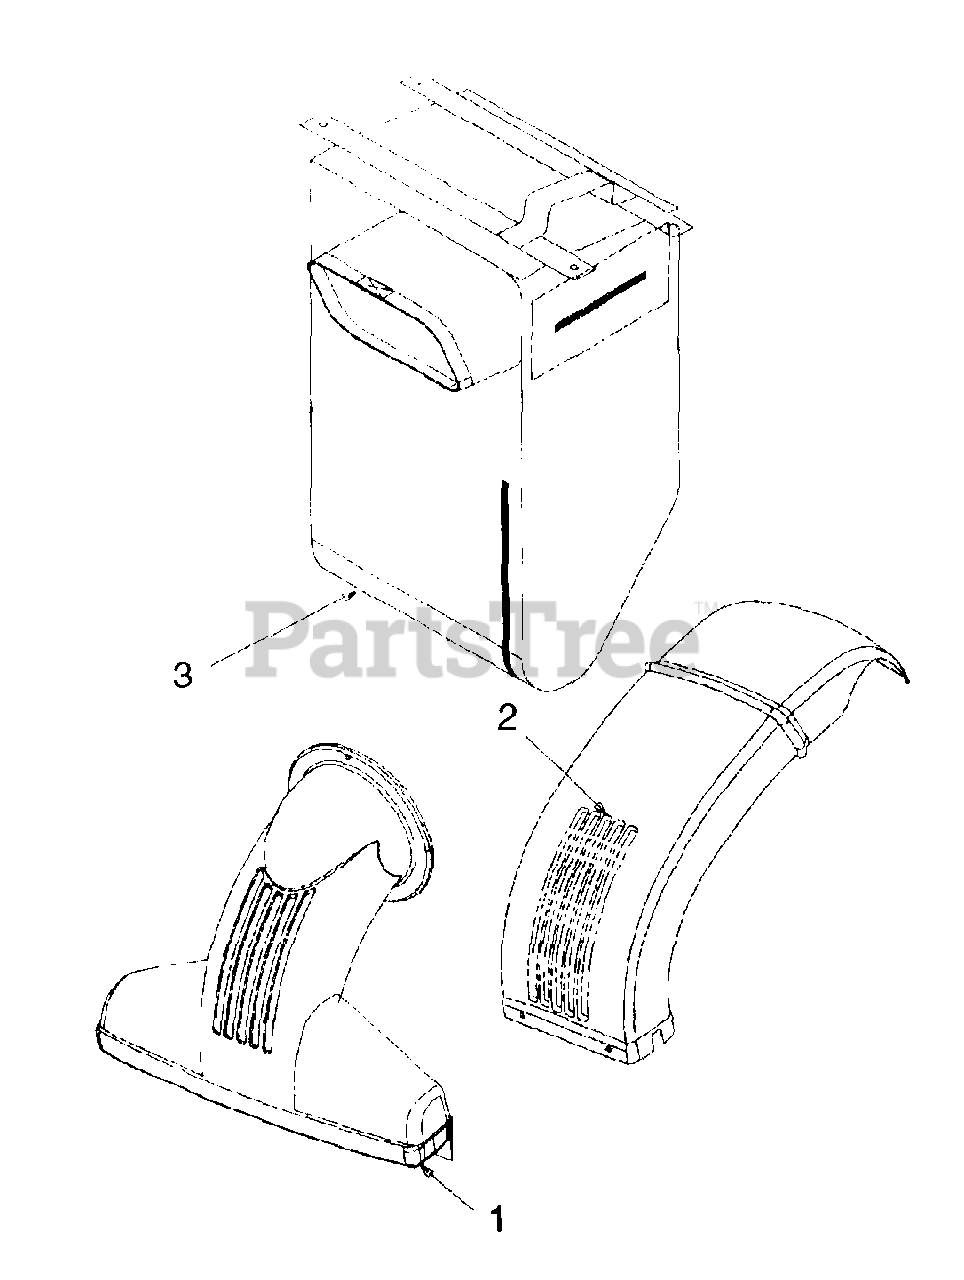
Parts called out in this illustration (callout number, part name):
1	Nozzle Assembly, Vacuum
2	Chute, Discharge
3	Bag, Vacuum
